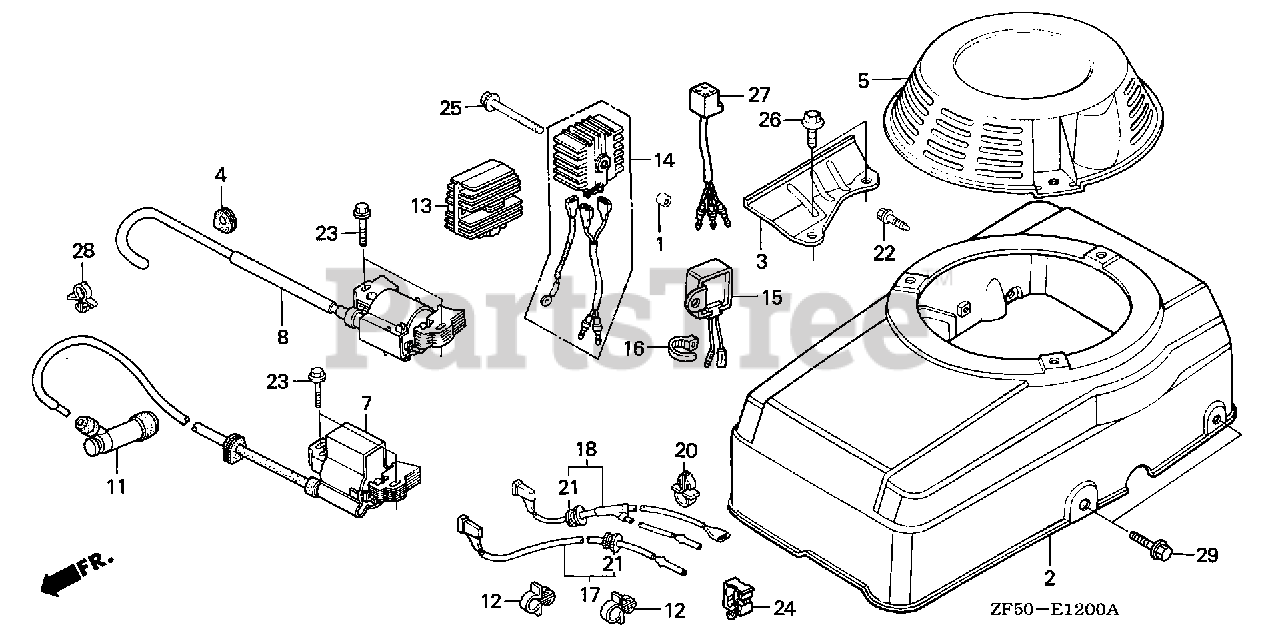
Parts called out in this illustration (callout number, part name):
1	SPACER, AIR CLEANER ELBOW
2	COVER, FAN *R8* (BRIGHT RED)
4	GROMMET, CORD
8	COIL ASSY., IGNITION
11	CAP ASSY., NOISE SUPPRESSOR
12	CLIP, IGNITION WIRE (8MM)
14	RECTIFIER ASSY., SILICON
16	BAND B1, WIRE
18	WIRE, STOP SWITCH
21	GROMMET, WIRE CORD
22	BOLT, FLANGE (6X12) (CT200)
23	BOLT, FLANGE (6X28) (CT200)
25	BOLT, FLANGE (6X40)
